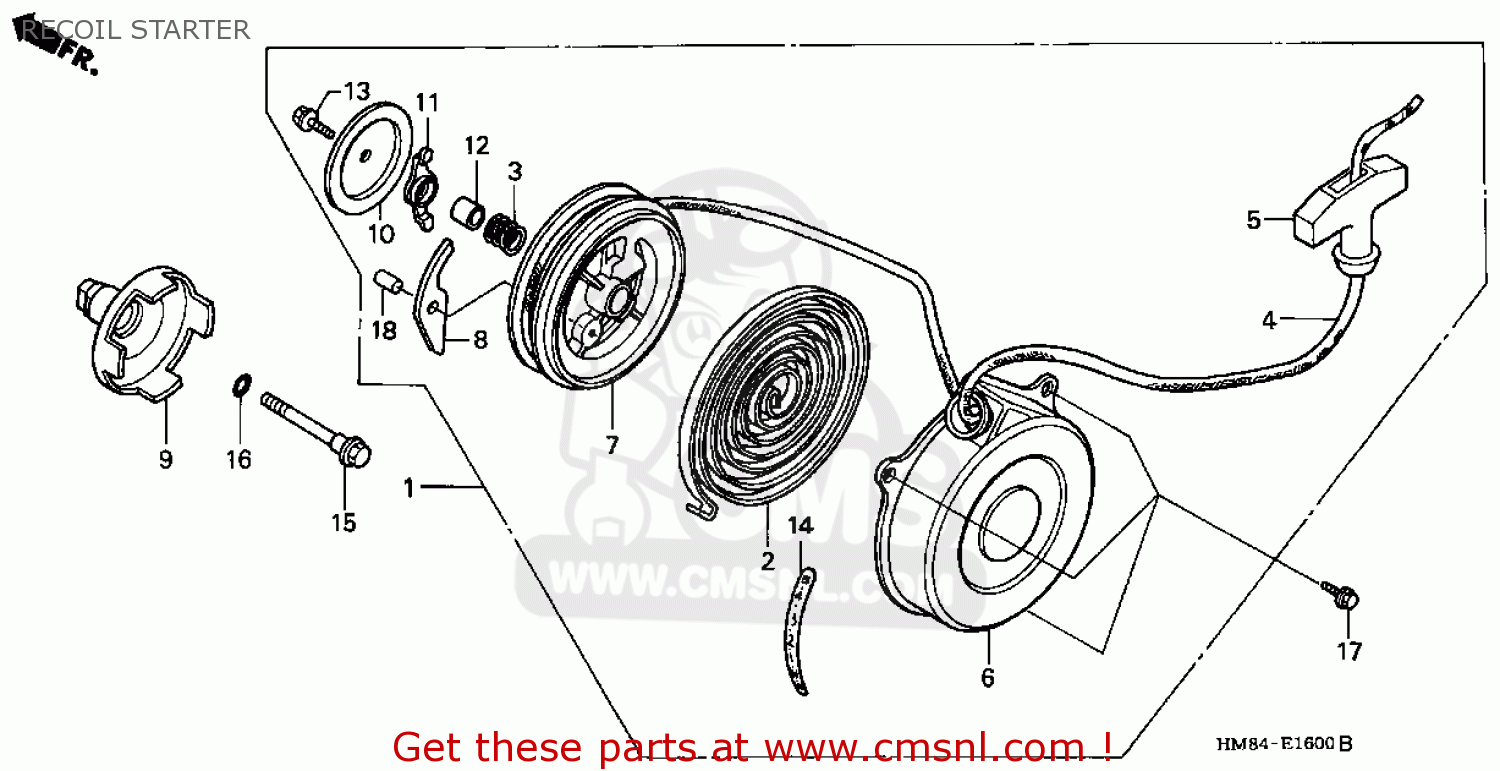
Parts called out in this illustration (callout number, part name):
1	STARTER ASSY,RECO
2	SPG,RCOIL STARTER
3	SPRING,FRICTION
4	ROPE,RECOIL START
5	KNOB STARTER
6	CASE COMP,RECOIL
7	REEL,RECOIL START
8	RATCHET,STARTER
9	PULLEY COMP,RECOI
10	PLATE,FRICTION
11	RATCHET GUIDE
12	COVER SPRING
13	BOLT
14	LABEL,SHIFT PATTE
15	BOLT,FRANGE UBS 1
16	O-RING,1.5X9.5
17	BOLT,FLANGE,SH,6X14
18	PIN,STARTER RATCH
